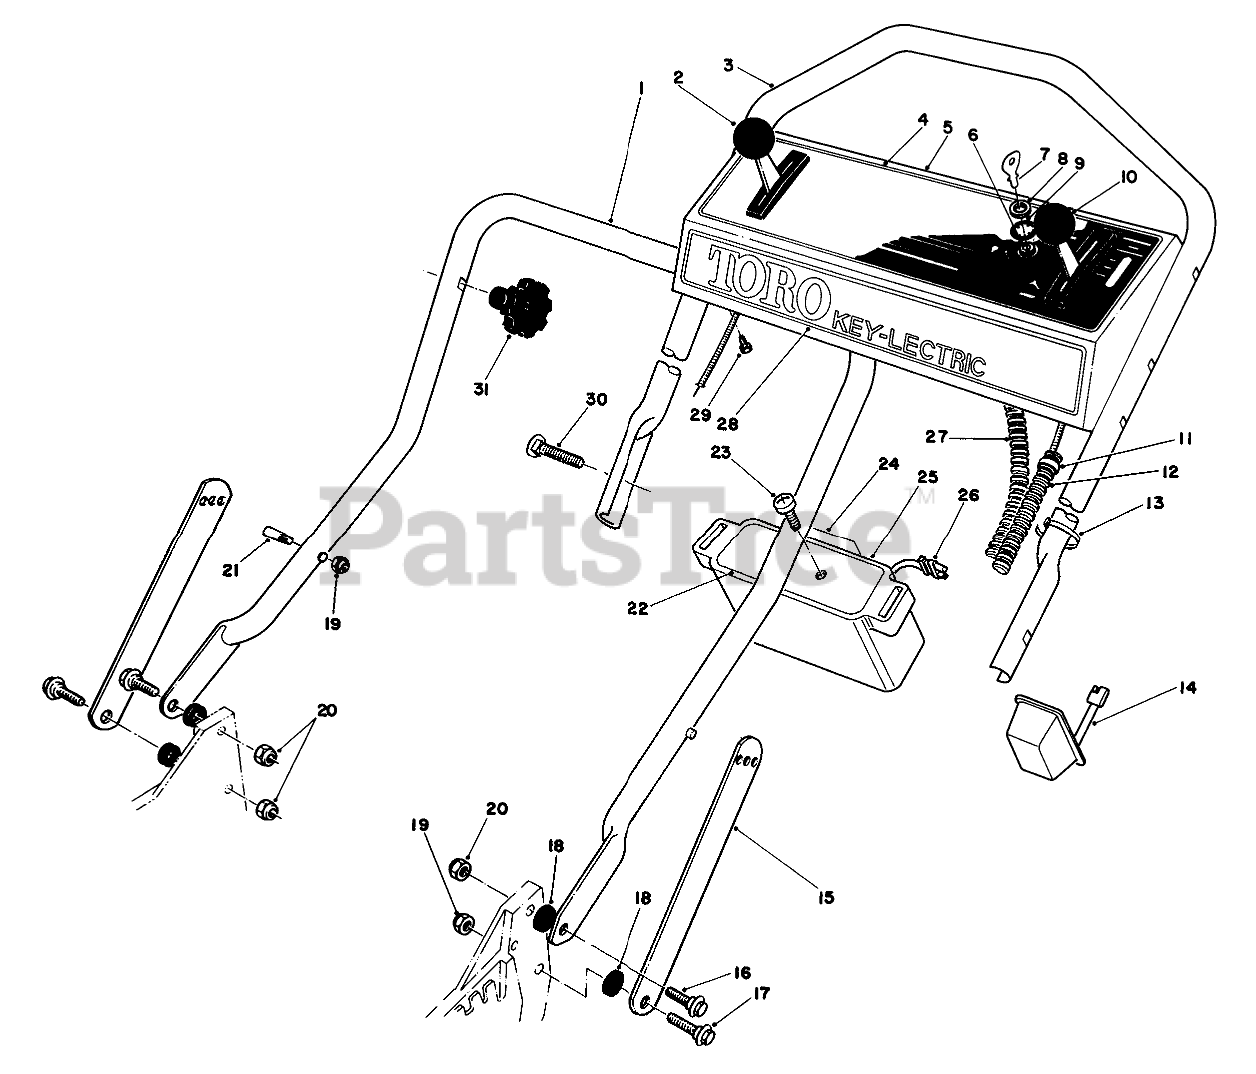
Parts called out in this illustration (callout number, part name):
1	Handle-Lower
2	GROUND SPEED CONTROL
3	Handle-Upper
4	OBS INSTR PANEL DECAL
5	Control Panel (Incl. Ref. #4)
6	Switch-Starter (Incl. Ref. #8 & 9)
7	Key
8	NUT-HH
9	WASHER-TOOTH, INTERNAL
10	SERVICE THROTTLE CONTRO
11	FITTING-RING
12	CONTROL CABLE COVER
13	TIE-CABLE
14	Charger
15	Handle Latch
16	SCREW-SHOULDER
17	SCREW-SHOULDER
18	SPACER
19	NUT-LOCK, NI
20	NUT-LOCK, NI
21	HANDLE PIN
22	BATTERY COVER
24	Decal
25	Battery Case
26	Plug & Wire Assembly
27	Wire Harness
28	Decal-Toro
29	SCREW-HWHTF
30	5/16-18 X 2 HNDLE SCREW
